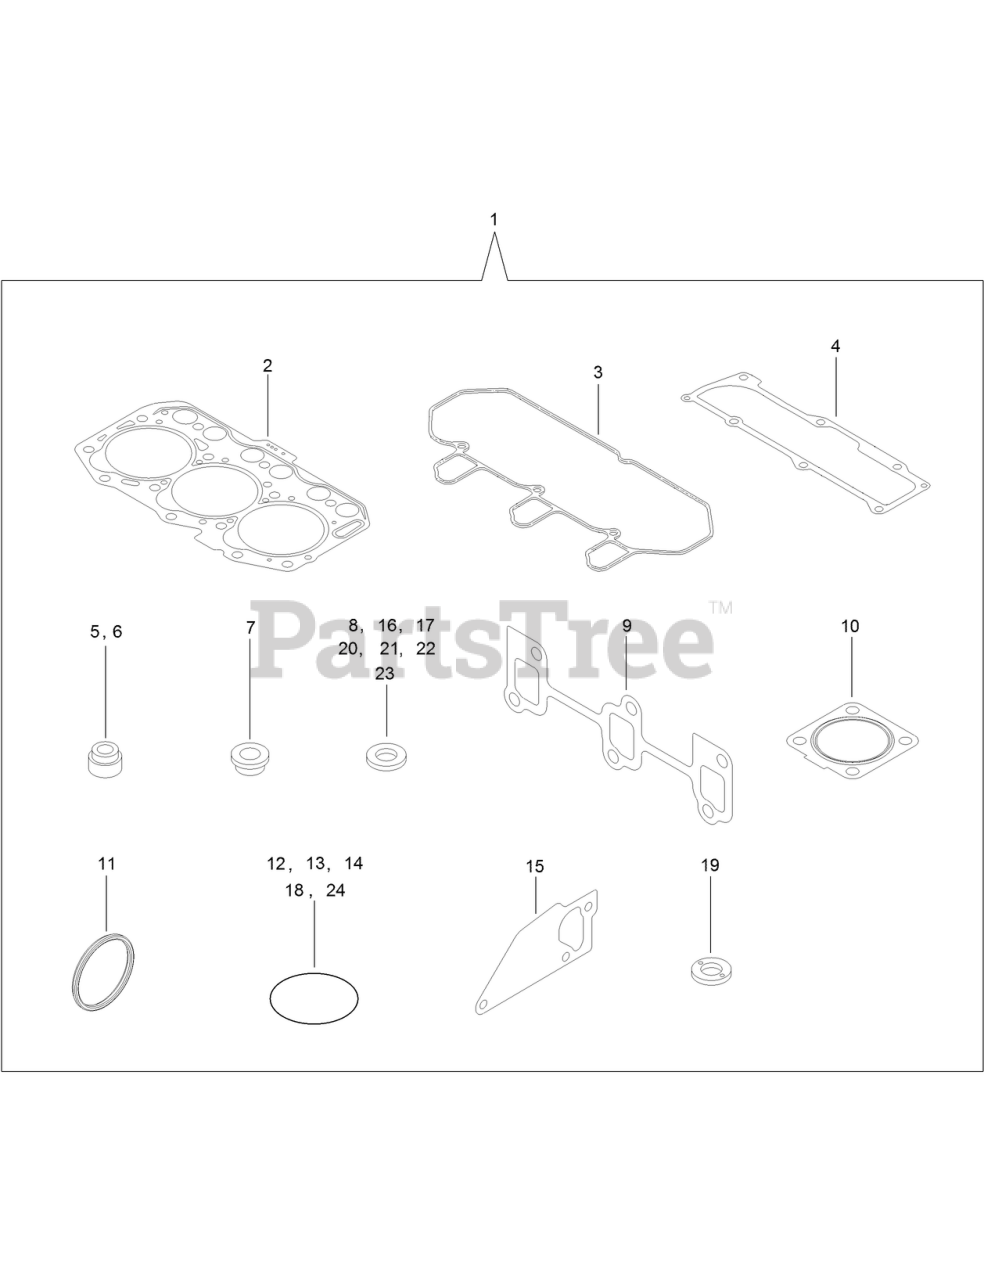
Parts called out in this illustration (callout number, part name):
1	GASKET SET
2	GASKET SET-HEAD
3	GASKET-BONNET
4	GASKET
5	SEAL-STEM, VALVE
6	SEAL-STEM, VALVE
7	PROTECTOR-NOZZLE
8	GASKET-NOZZLE
9	GASKET-EXH MANIFOLD
10	GASKET-SILENCER
11	PACKING-WASHER
12	O-RING
13	O-RING
14	O-RING
15	GASKET-WATER PUMP
16	GASKET
17	GASKET
18	O-RING
19	GASKET
20	WASHER-SEAL
21	WASHER-SEAL
22	WASHER-SEAL
23	GASKET
24	O-RING
